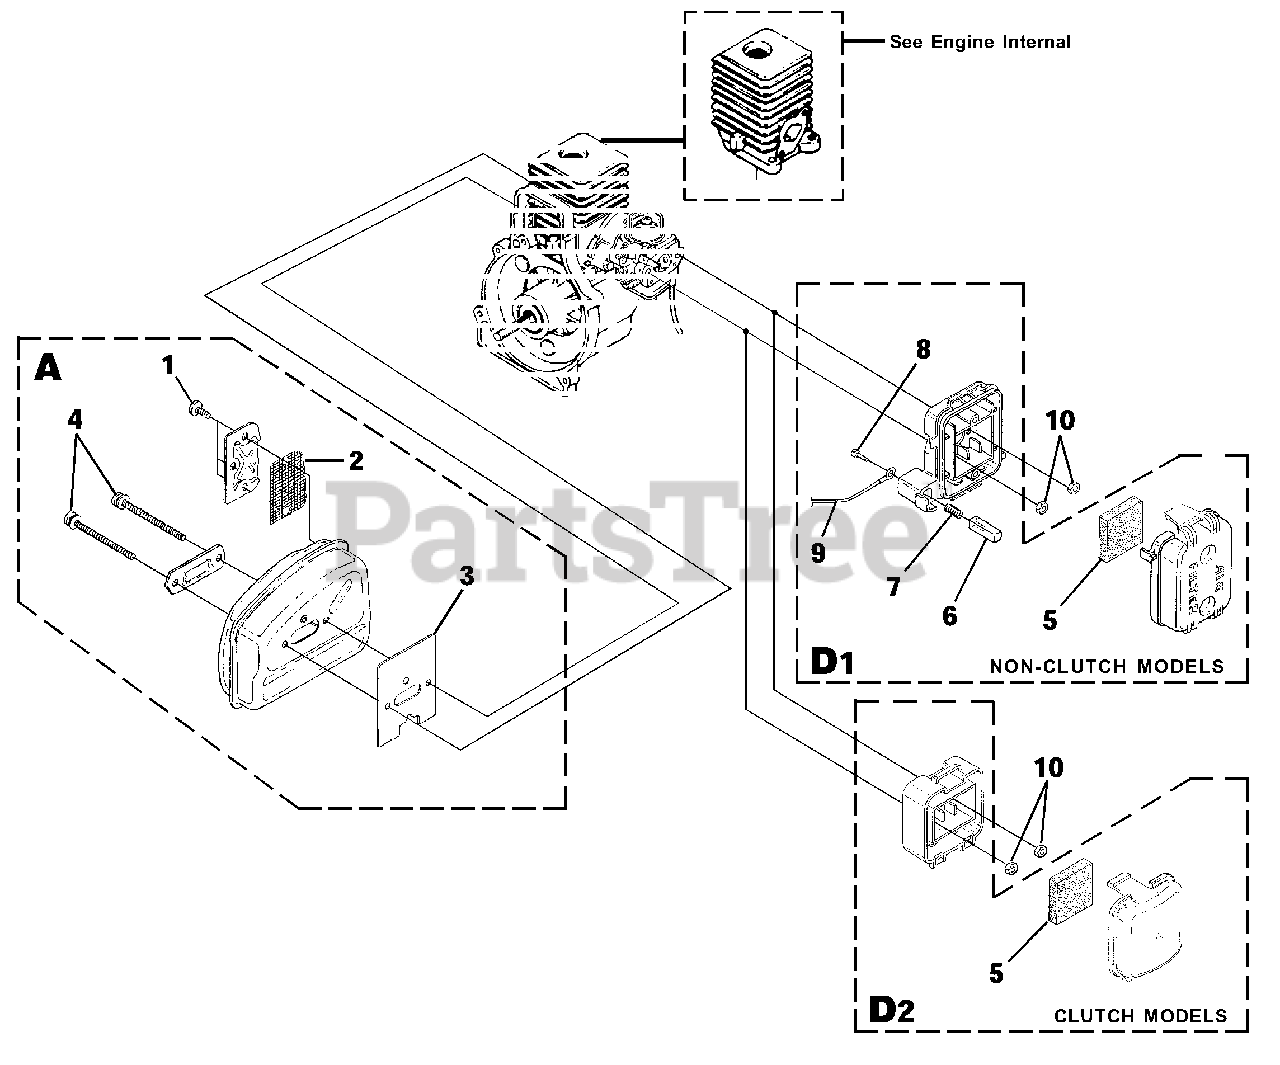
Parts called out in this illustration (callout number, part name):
1	SCREW, Taptite- (8-32 X 3/8")
2	SCREEN-Spark
3	GASKET-Muffler
4	SCREW, Truss Hd. - (10-24 X 2.188)
5	FILTER-Air
5	FILTER-AIR
6	BUTTON-Switch
7	SPRING-Compression
8	SCREW-Thread Form (6-19 x 1/2")
9	LEAD-Electrical
10	NUT-Hex (10-24)
A	MUFFLER ASSY.
D1	AIR FILTER KIT (Non-Clutch)
D2	AIR FILTER KIT (Clutch)
